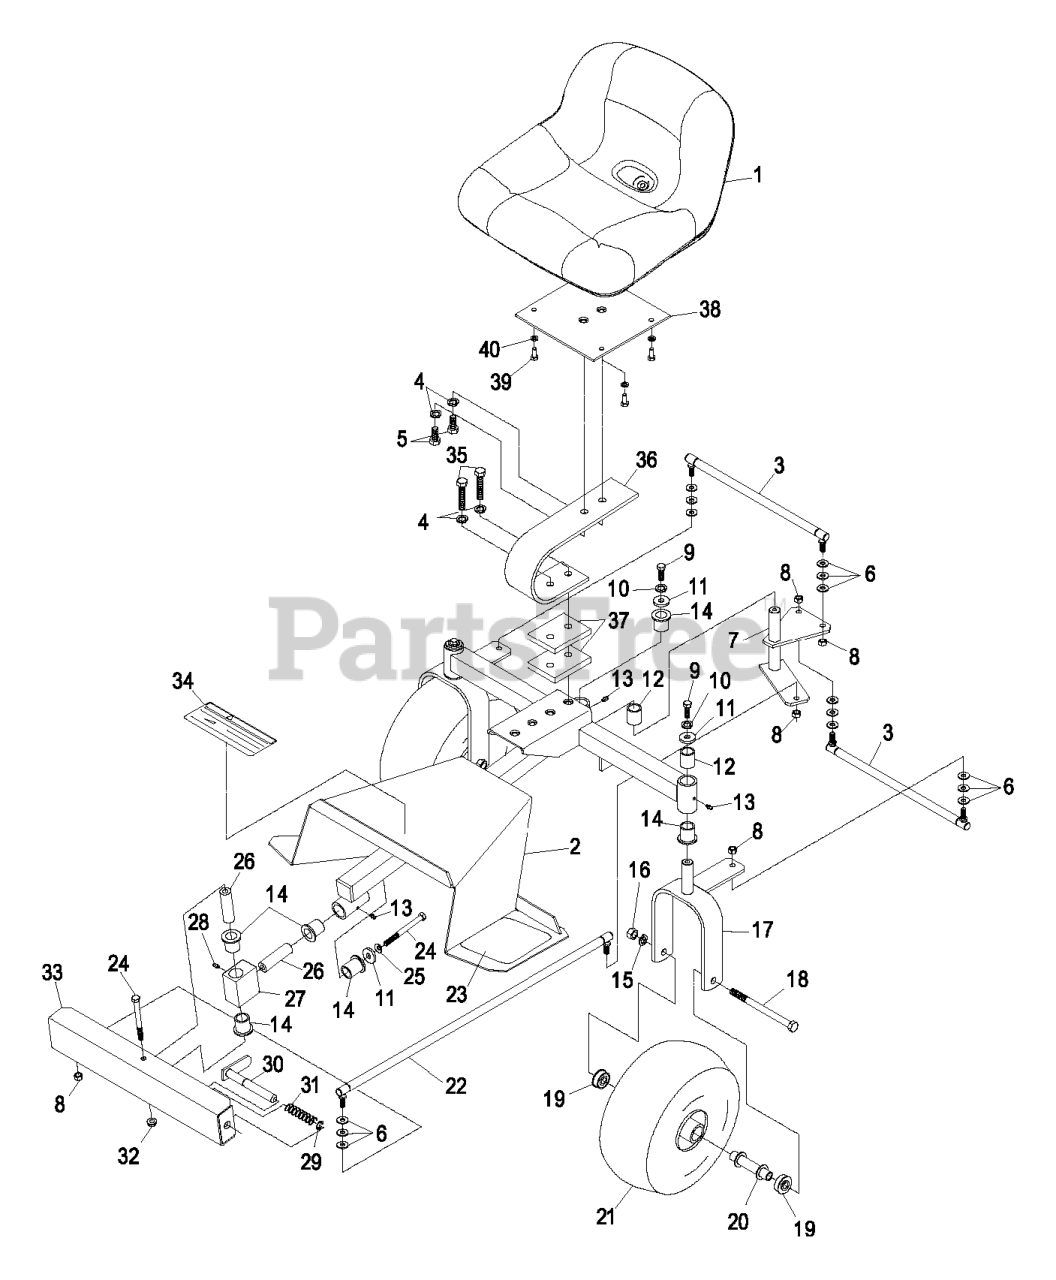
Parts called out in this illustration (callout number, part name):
3	ROD,STABILIZING
4	WASHER-LOCK
5	SCREW-HH
6	WASHER-FLAT
7	WLD,CRANK
9	SCREW-HH
10	WASHER-LOCK
12	BEARING,STRAIGHT
13	FITTING-GREASE
14	BEARING-FLANGED
15	WASHER-LOCK
16	NUT-HH
17	WLD,WHEEL SUPPORT
18	SCREW-HH
20	WLD,WHEEL SPACER
22	ROD-STEERING
23	PAD,ANTI SKID
24	SCREW-HH
25	WASHER-BELLEVILLE
26	PIN,CONNECTING
27	ASM,MOUNTING SWIVEL
28	FITTING-GREASE
31	SPRING,HITCH RELEASE
32	NUT-HHF, WHIZ
33	WLD,HITCH
35	SCREW-HH
36	SPRING,SULKY SEAT
38	WLD, SEAT MOUNT
39	SCREW-HH
40	WASHER-LOCK
